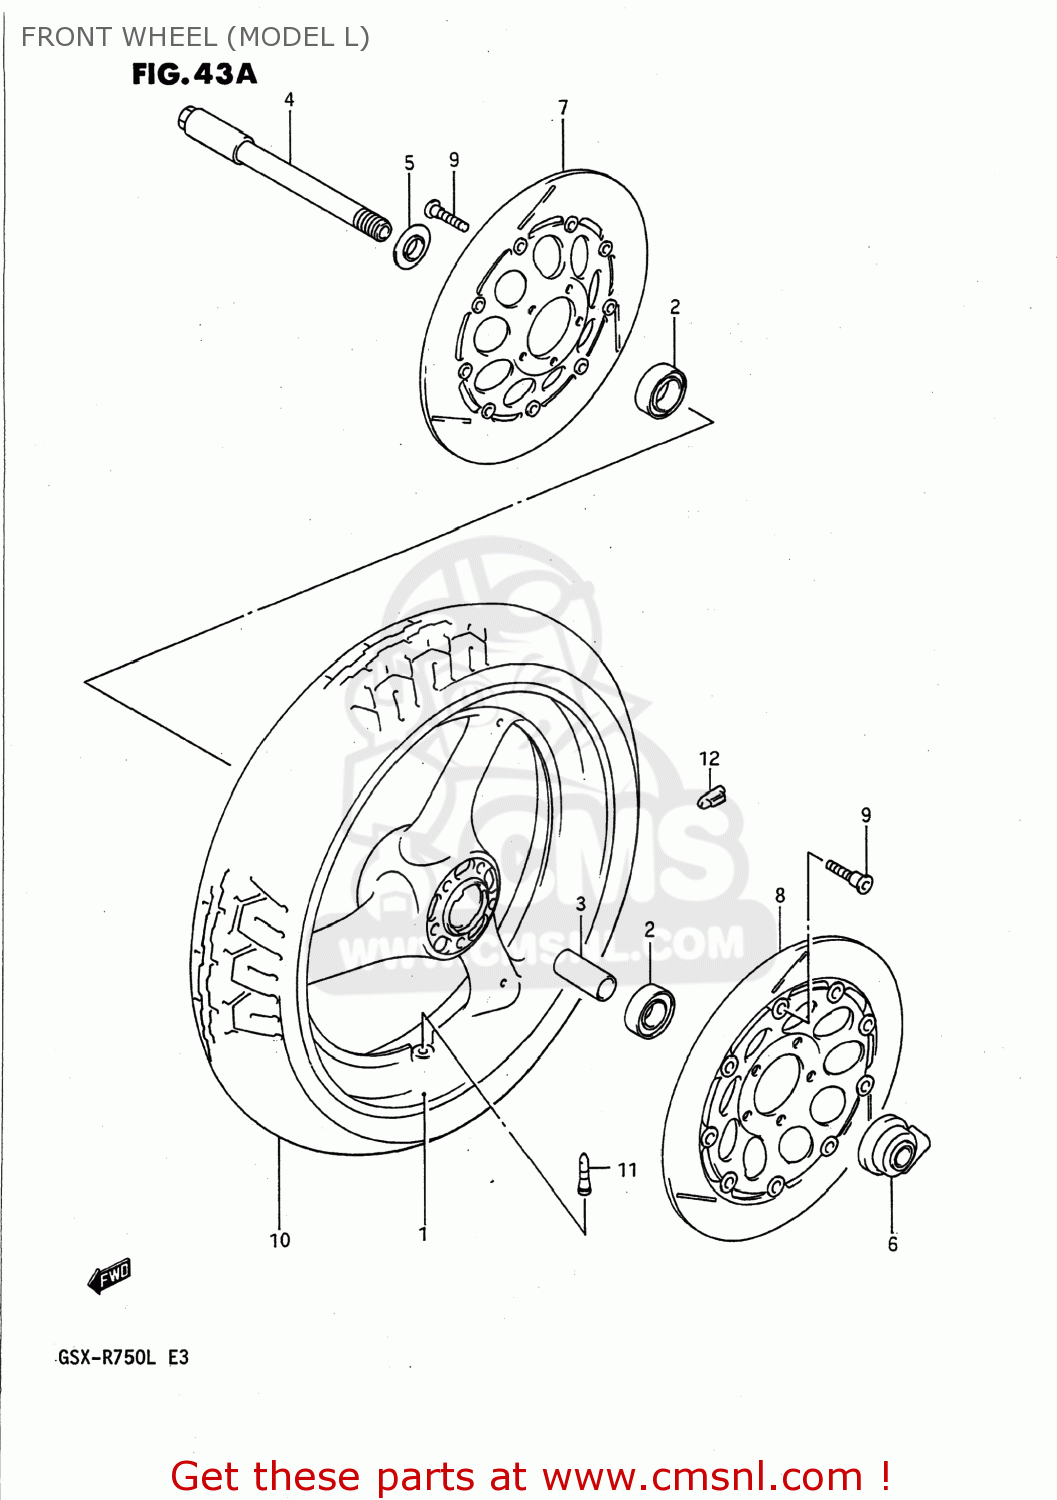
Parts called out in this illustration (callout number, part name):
1	WHEEL,FRONT
2	BEARING
3	SPACER(20.8X27.2X74)
4	AXLE,FR
5	SPACER,FR HUB BEARING,R
6	BOX ASSEMBLY,SPEEDOMETER GEAR
7	DISC,BRAKE
8	DISC,BRAKE
9	BOLT
10	TIRE,FRONT
11	VALVE ASSY,WHEEL RIM(TR412)
12	BALANCER,WHEEL
